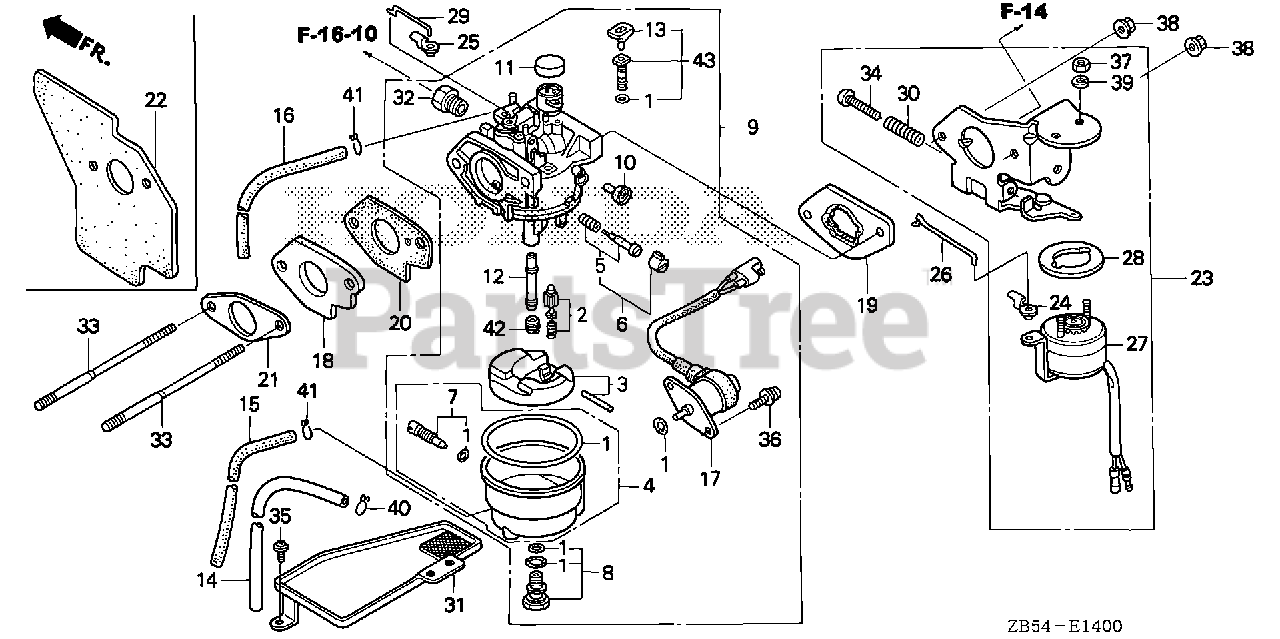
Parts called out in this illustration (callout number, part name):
1	GASKET SET
2	VALVE SET, FLOAT
3	FLOAT SET
4	CHAMBER SET, FLOAT
6	SCREW SET (Honda Code 4219879). (CARBURETOR NO.)
7	SCREW SET, DRAIN (ADVENTURE GREEN) (CARBURETOR NO.)
8	SCREW SET
9	CARBURETOR ASSY. (BE77E B)
10	SCREW, THROTTLE STOP
11	CAP, CHOKE LEVER DUST
12	NOZZLE, MAIN
13	COLLAR, SET
14	TUBE, FUEL DRAIN
15	TUBE, DRAIN
16	TUBE, AIR VENT
17	VALVE, SOLENOID
18	INSULATOR, CARBURETOR
19	SPACER, CARBURETOR
20	GASKET, CARBURETOR
21	GASKET, INSULATOR
23	STAY ASSY., SOLENOID
24	JOINT, ROD
25	JOINT, ROD
26	ROD, CHOKE SOLENOID
27	SOLENOID ASSY.
28	SPACER, CHOKE SOLENOID
29	ROD, GOVERNOR ARM
30	SPRING, CONTROL ADJUSTING Use from Engine SN 2327377.
31	COVER, FUEL DRAIN
32	NUT, JOINT
33	BOLT, STUD (8X100)
34	SCREW, PAN (5X28)
35	SCREW-WASHER (5X12)
36	SCREW-WASHER (5X12)
37	NUT, HEX. (4MM)
38	NUT, FLANGE (6MM)
39	WASHER, SPRING (4MM)
40	CLIP, TUBE (A10)
41	CLIP, TUBE (A10)
42	JET, MAIN (#95)
42	JET, MAIN (#98) Use from Engine SN BE87A A to BE87A A.
42	JET, MAIN (#100) Use from Engine SN BE87A A to BE87A A.
43	JET SET, PILOT (#40) (ADVENTURE GREEN) (CARBURETOR NO.)
